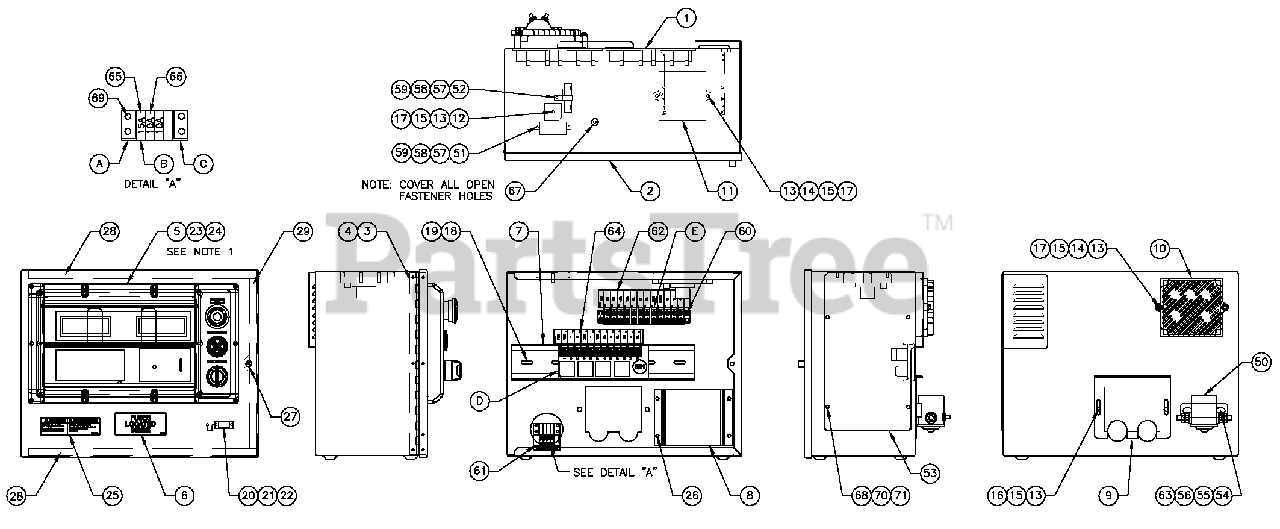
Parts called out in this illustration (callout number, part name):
1	ENCLH/G CONTROL PANEL
2	COVER CONTROL PANEL
3	HINGE CONTINUOUS H PANEL
4	RIVET POP .125X .275SS
5	ASSYPROGRAMMEDH-100
6	DECAL FUSES LOCATED INSIDE
7	RAILSNAPTRACK PCB HOLDER BULK (12" LG)
8	ASSYPCB 2AMP 12V ULBATTCHGR
9	PLATE HARNESS CLAMP
10	ASSYPCB PWRAVRW/AMP HEADER
11	ASSYPCB BOSCH GOV DRIVER
12	DIO BRIDGE25A 600V
13	WASHER LOCK M5
14	SCREW PPHM M5-0.8X 30SS
15	WASHER FLAT M5
16	SCREW HHPM M5 0.8X12
17	NUT HEXM5 0.8G8 YELCHR
18	WASHER FLAT M4
19	SCREW PHTT M4-0.7X 10ZYC
20	CONN DUST CAP W/CHAIN DB9
21	WASHER FLAT M3.5
22	SCREW PHTT M3.5 0.6X 10
23	SCREW PPHM M4-0.7X 8 BLXOX
24	WASHER LOCK #8 M4
25	DECAL WRNB ATT CHRG12/24VBI
26	SCREW PHTT M4-0.7X 12ZYC
27	M5 0.8 CAPTIVE PANEL KNLDHD
28	SEAL COVER 3.18 X 12.7X 382
29	SEAL COVER 3.18 X 12.7X 283
50	RELAY CONTACTOR 12VDC
53	COVER CONTROL PANEL SIDE
54	SCREW HHC 1/4-20X3/4G5
55	WASHER FLAT M6-1/4
56	WASHER LOCK M6-1/4
57	WASHER LOCK M3
58	NUT HEXM3 0.5G8 YELCHR
59	WASHER FLAT M3
60	SCREW PHTT#6-32X5/8ZYC
61	DECAL CPL CONTROL PANEL FUSES
62	DECAL CPL 5.4/6.8LTB3
63	NUT HEX 1/4-20 STEEL
64	DECAL CPL 5.4/6.8L RELAY BOARD
65	FUSE ATO TYPE 15 AMP (BLUE)
66	FUSE ATO TYPE 10 AMP (RED)
67	SEAL WEATHER.45"DIA
68	SCREW PPHM M5-0.8X 12ZNC
69	SCREW PHTT#6-32X3/8ZYC
70	WASHER FLAT M5
71	WASHER LOCK M5
A	ADPTR RH SIDE WICKMANN 178.6191
B	HOLDERFUSE WICKMANN 178.6150
C	ADPTR LH SIDE WICKMANN 178.6192
D	ASSYPCB G PANEL RELAY 12VDC
E	BLOCK TERM 20A 12X 6 X1100V
